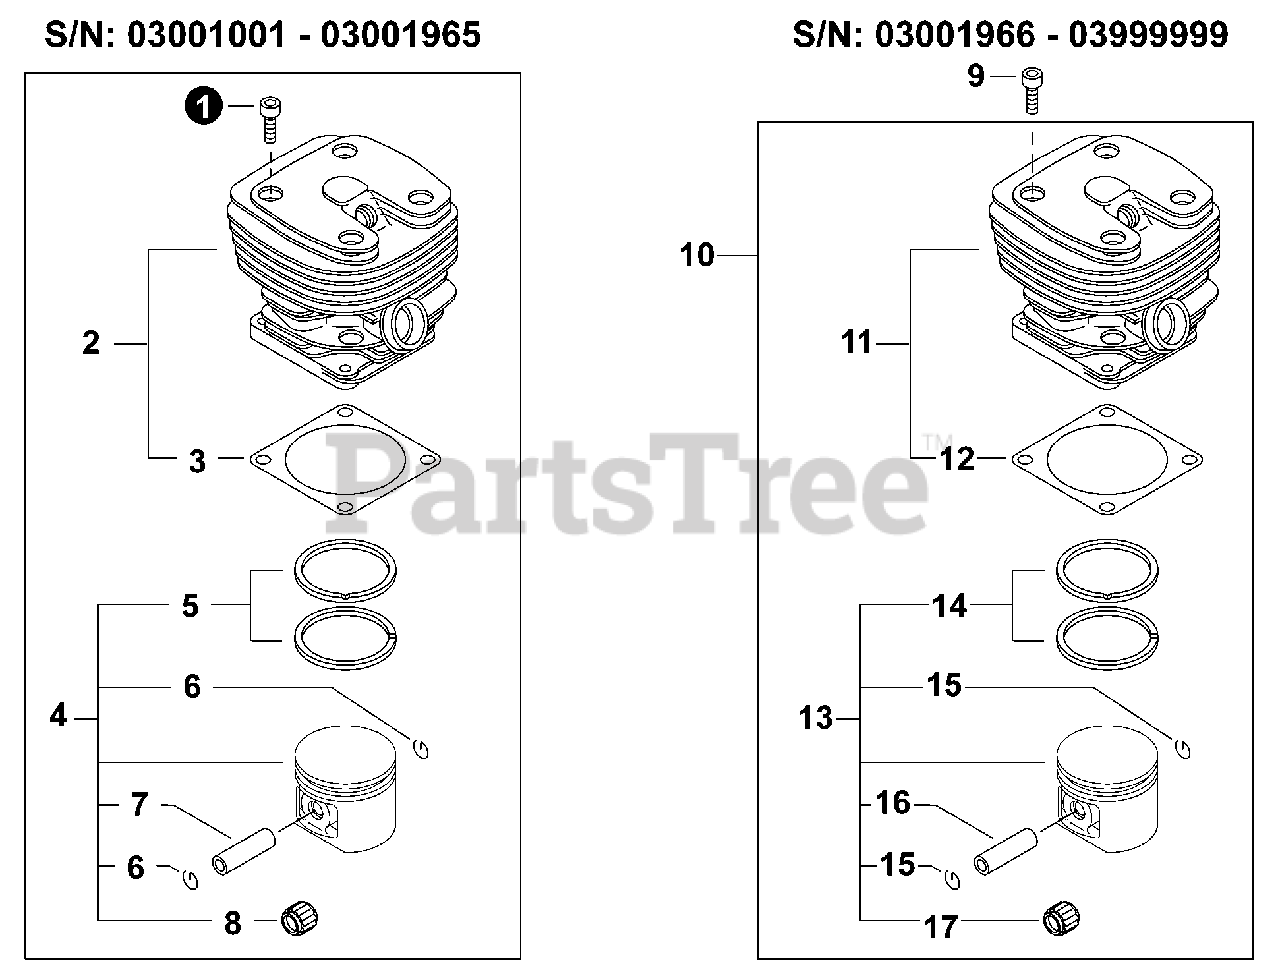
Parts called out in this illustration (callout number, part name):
1	BOLT 6x25
2	CYLINDER KIT
3	GASKET, CYLINDER
4	PISTON KIT
5	RING, PISTON
6	RING, RETAINING
7	PIN, PISTON
8	BEARING, NEEDLE
9	BOLT 6x25
10	CYLINDER/PISTON KIT
11	CYLINDER ASSY
12	GASKET, CYLINDER
13	PISTON KIT
14	RING, PISTON
15	RING, RETAINING
16	PIN, PISTON
17	BEARING, NEEDLE
